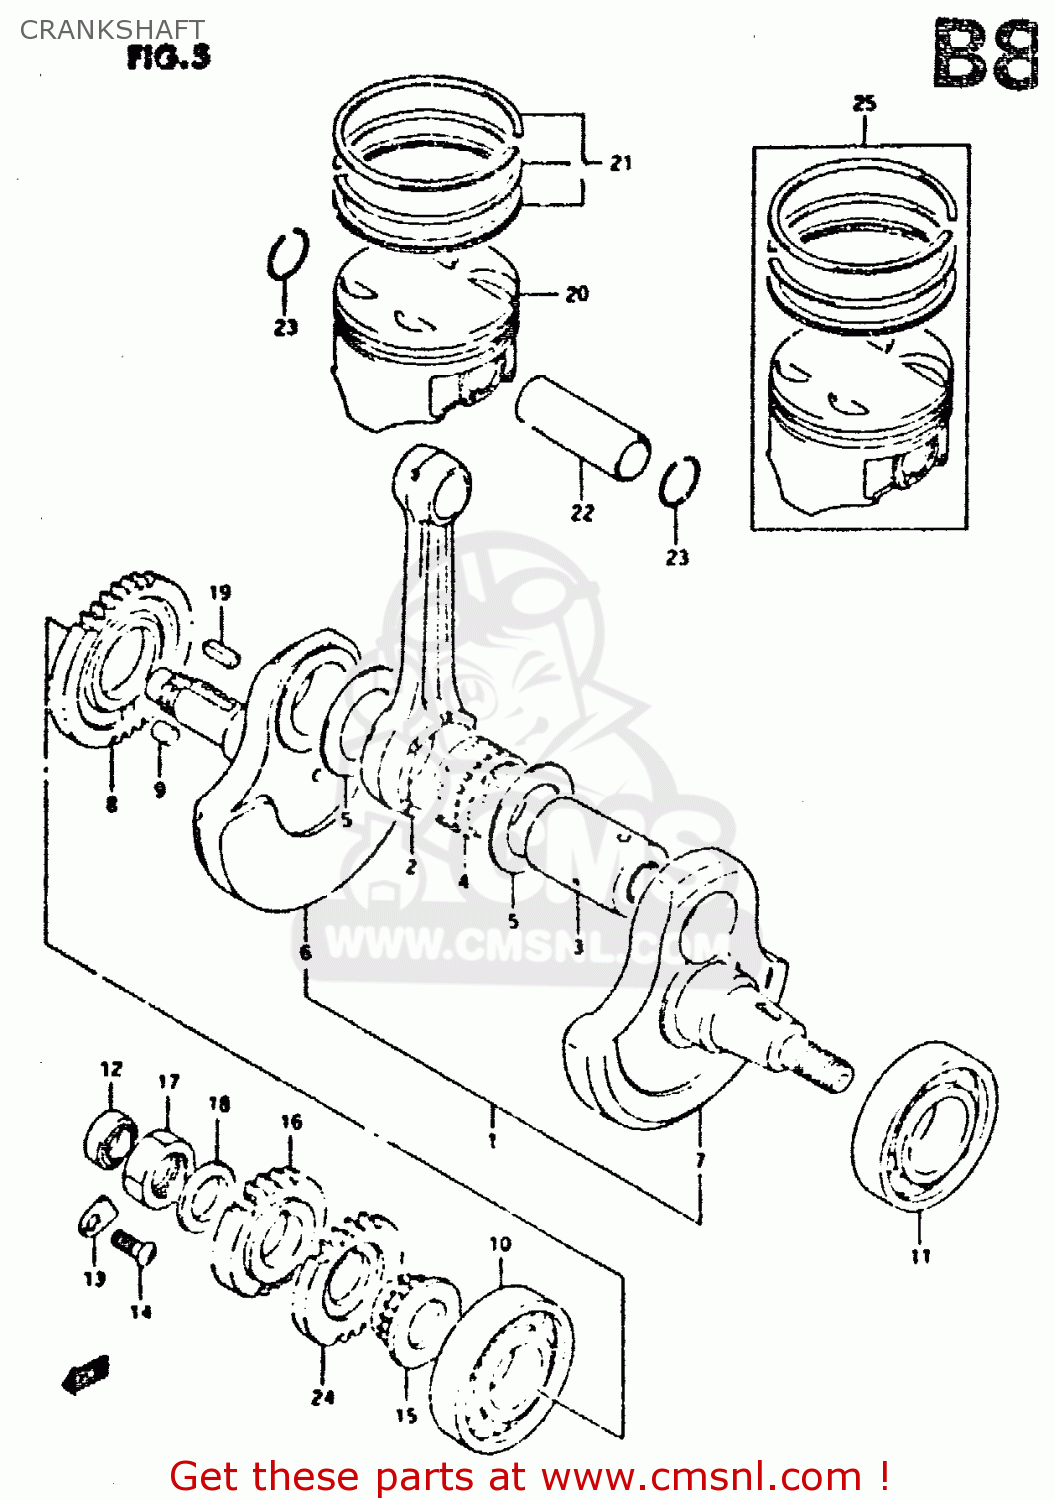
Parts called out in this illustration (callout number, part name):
1	CRANKSHAFT ASSY
2	ROD,CONNECTING
3	PIN COMP,CRANK
4	BEARING(34X43X22)
5	WASHER(34X52X1)
6	CRANKSHAFT,R
7	CRANKSHAFT,L
8	GEAR,CRANK BAL DRIVE(NT:37)
9	PIN
10	BEARING(30X72X19)
11	BEARING(35X72X17)
12	SEAL,OIL(14X24X6)
13	RETAINER,BEARING
14	SCREW
15	SPROCKET,CAM CHAIN DRIVE
16	GEAR,PRIMARY DRIVE
17	NUT
18	WASHER
19	KEY
20	PISTON
21	RING SET,PISTON
22	PIN,PISTON
23	CIRCLIP,PISTON PIN
24	GEAR,OIL PUMP DRIVE (NT
25	PISTON SET(OS:0.5)
